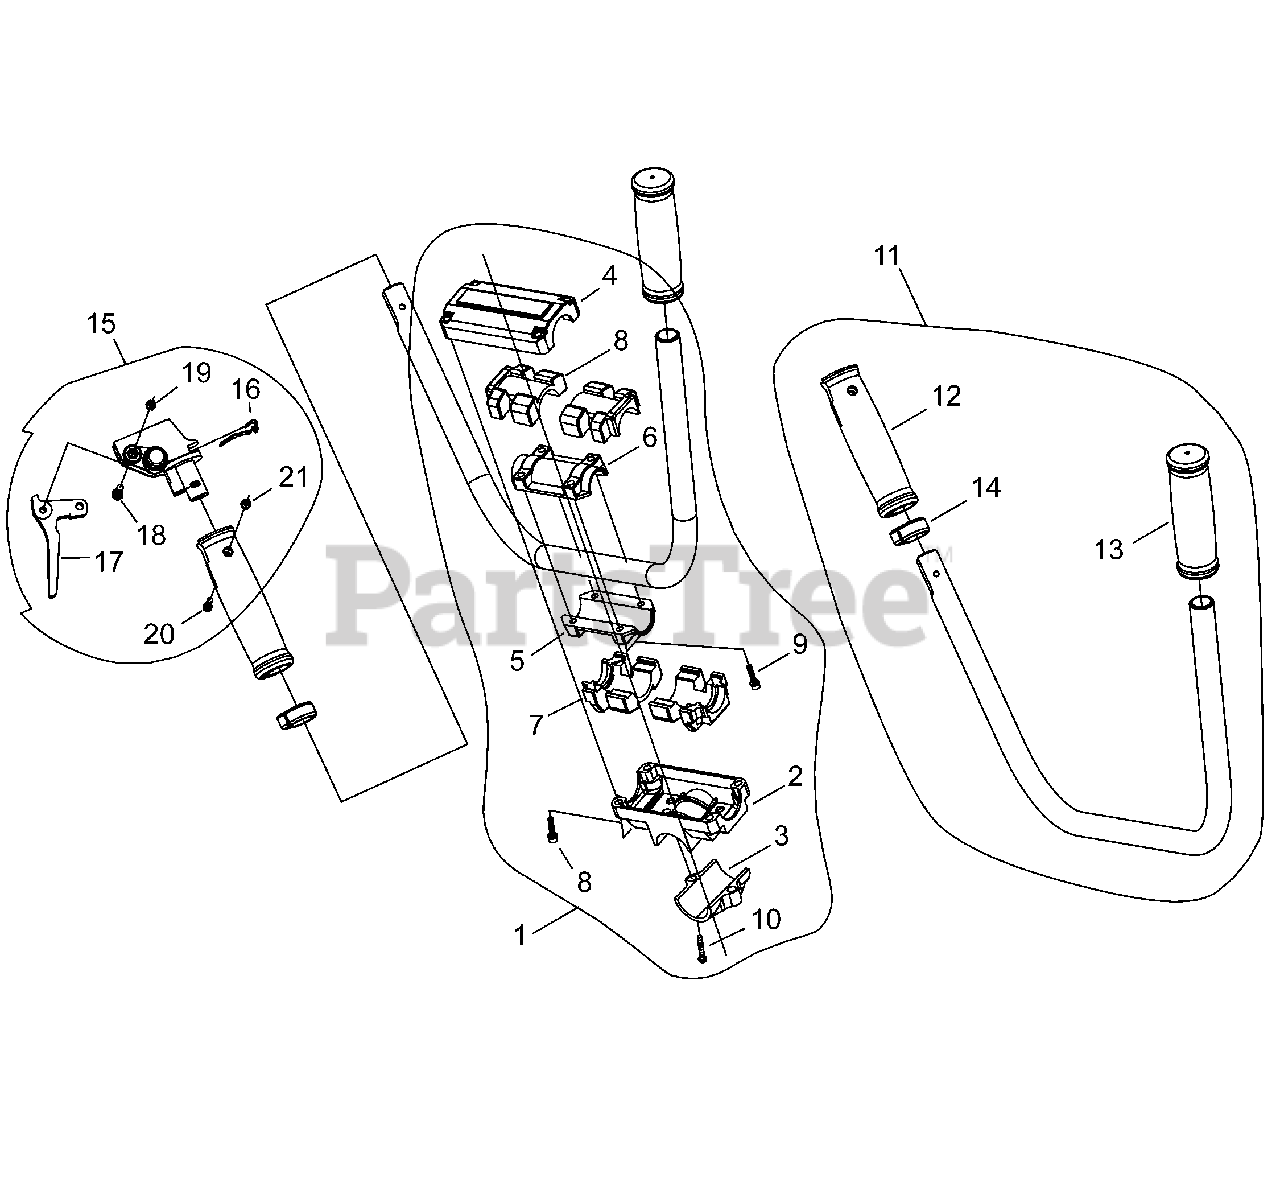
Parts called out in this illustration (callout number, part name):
1	BRACKET KIT, HANDLEBAR
2	BRACKET, HANDLE Ø28
3	CLAMP, LOWER Ø28
4	CLAMP, UPPER
5	CLAMP, LOWER
6	CLAMP, UPPER
7	CUSHION, LOWER
8	CUSHION, UPPER
9	BOLT M5×25
10	SCREW M6×25
11	HANDLEBAR ASSY
12	GRIP, RIGHT
13	GRIP, LEFT
14	HOLDER, THROTTLE CABLE
15	THROTTLE CONTROL ASSY
16	STOPPER, THROTTLE TRIGGER
17	TRIGGER, THROTTLE
18	BOLT
19	NUT, LOCK M5
20	BOLT M4×24
21	NUT, NYLON M4
